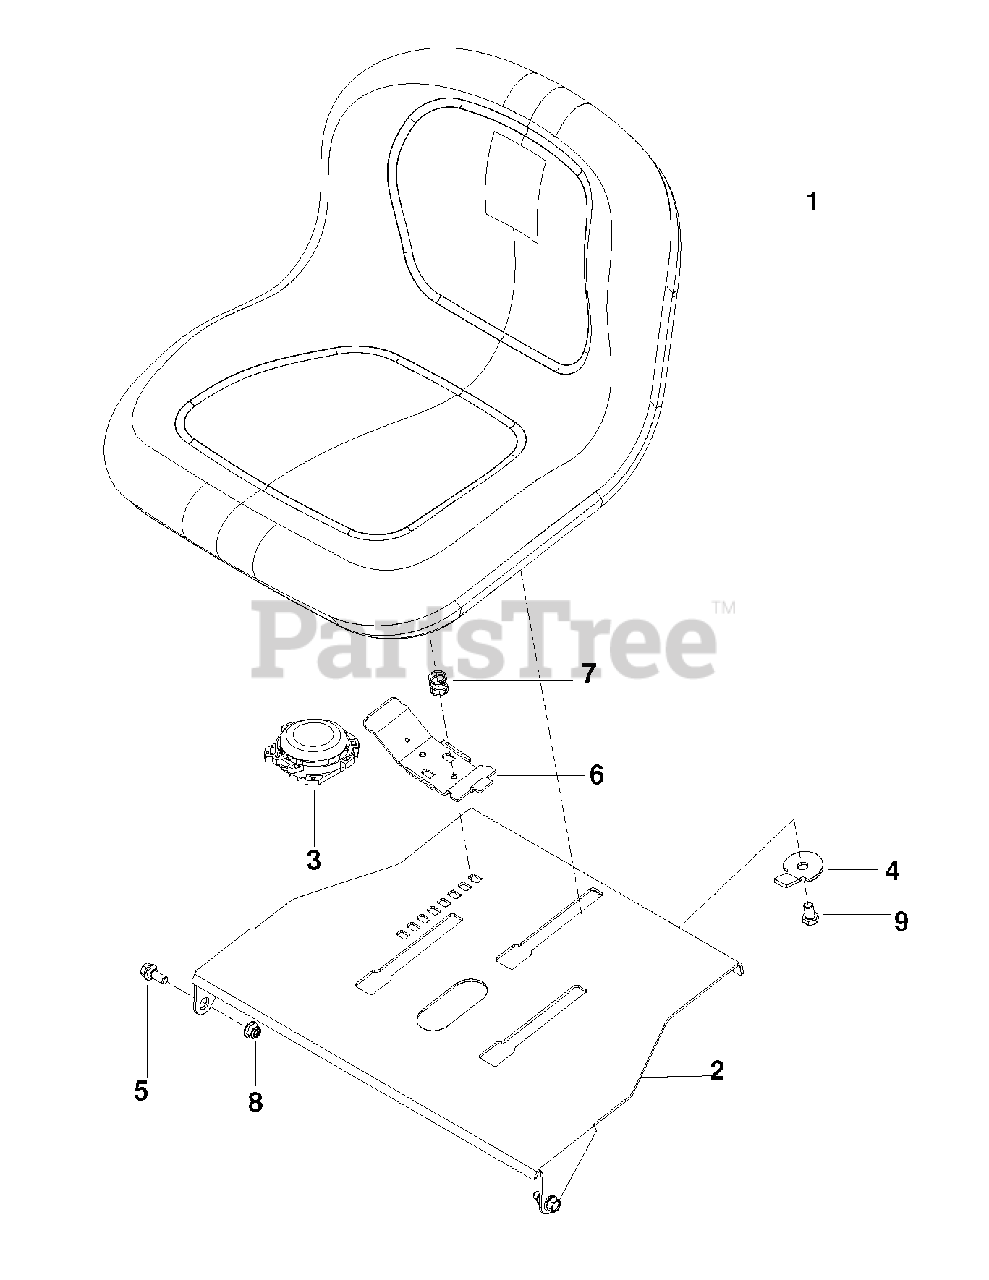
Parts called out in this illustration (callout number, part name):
1	SEAT
2	PLATE, SEAT
3	SWITCH, SEAT
4	STOP, SEAT
5	BOLT 5/16-SHOULDER
6	HANDLE, SEAT SLIDE
7	SPRING, SEAT SLIDE
8	NUT 5/16-18 FLANGE NYLOC
9	HCS 3/8-16 x 5/8
